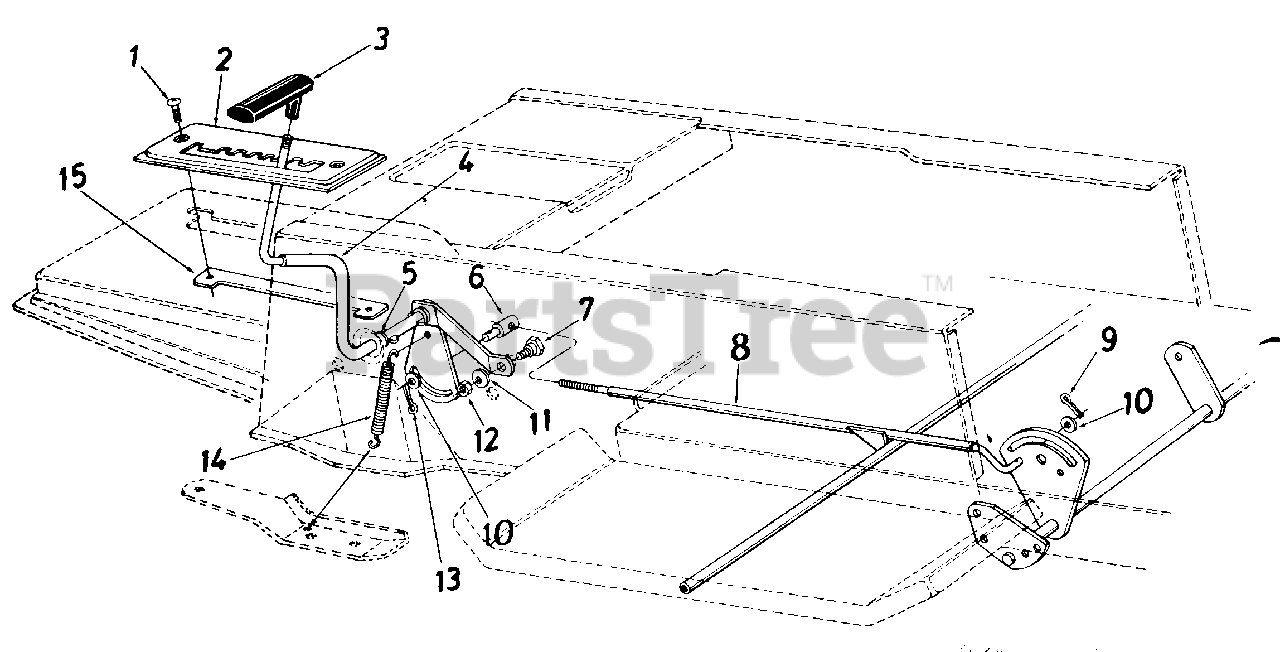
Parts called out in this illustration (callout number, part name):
1	Truss Mach. Scr. 1/4-20 x .75" Lg.
2	Speed Selector Plate 5-Speed
4	Speed Selector Cam Ass'y.
5	Flat Washer .53" I.D. x .93" O.D.
6	Ferrule 3/8-24 x .37" Dia.
7	Shoulder Bolt .435" Dia. x . 1 60
8	Speed Control Rod Ass'y.
9	Cotter Pin 3/32" Dia. x .75" Lg. *
10	Fl-Wash. .469" I.D. x .88" O.D.
11	L-Wash. 5/16" I.D*
12	Hex Nut 5/16-18 Thd*
13	Cotter Pin 3/32" Dia. x .75" Lg. *
14	Spring .38" O.D. x 3.18" Lg.
15	Clamping Plate
